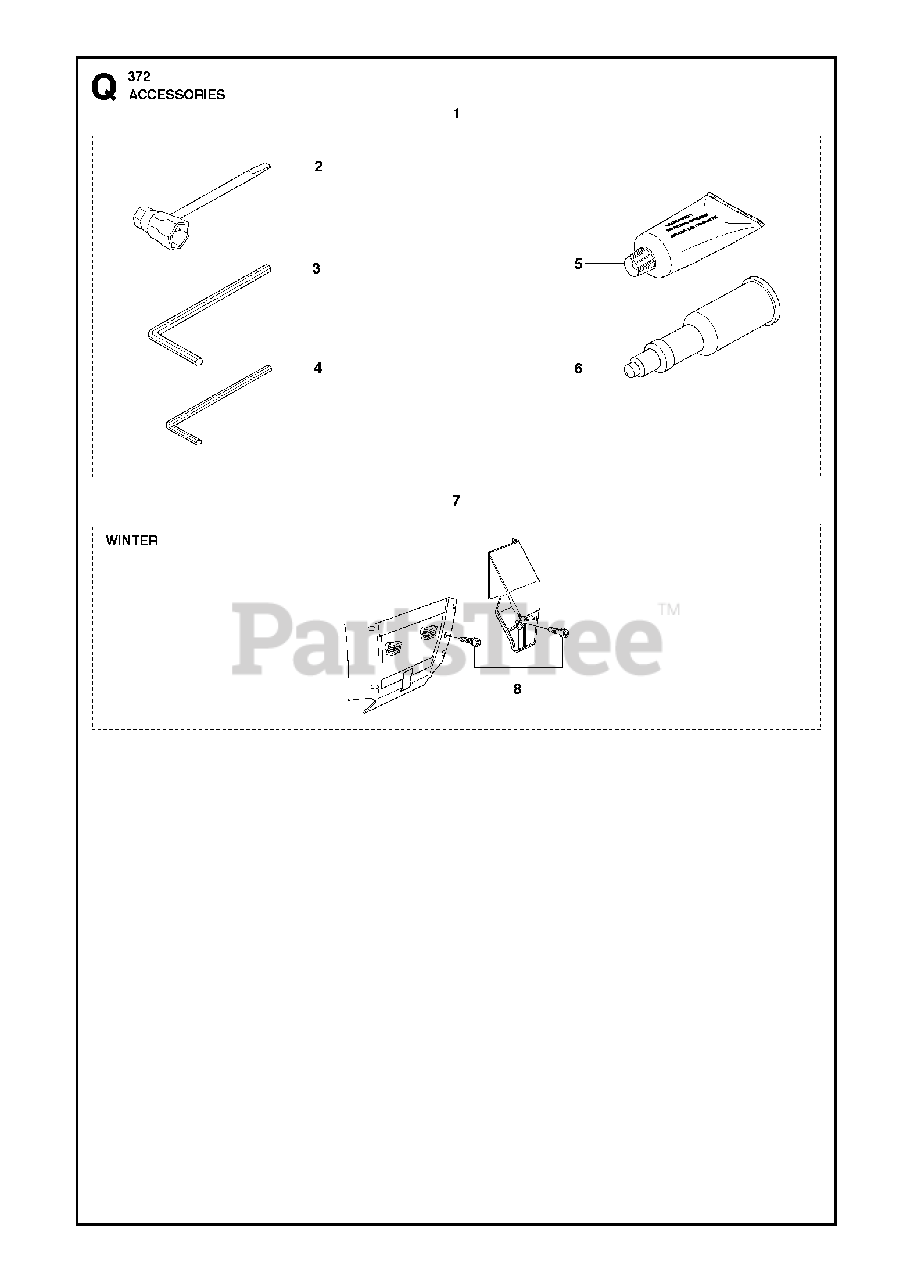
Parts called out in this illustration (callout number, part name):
1	TOOL KIT
2	COMBI TOOL
3	L-SPANNER
4	L-SPANNER
5	GREASE
6	Grease Gun
7	WINTER KIT
8	SCREW
